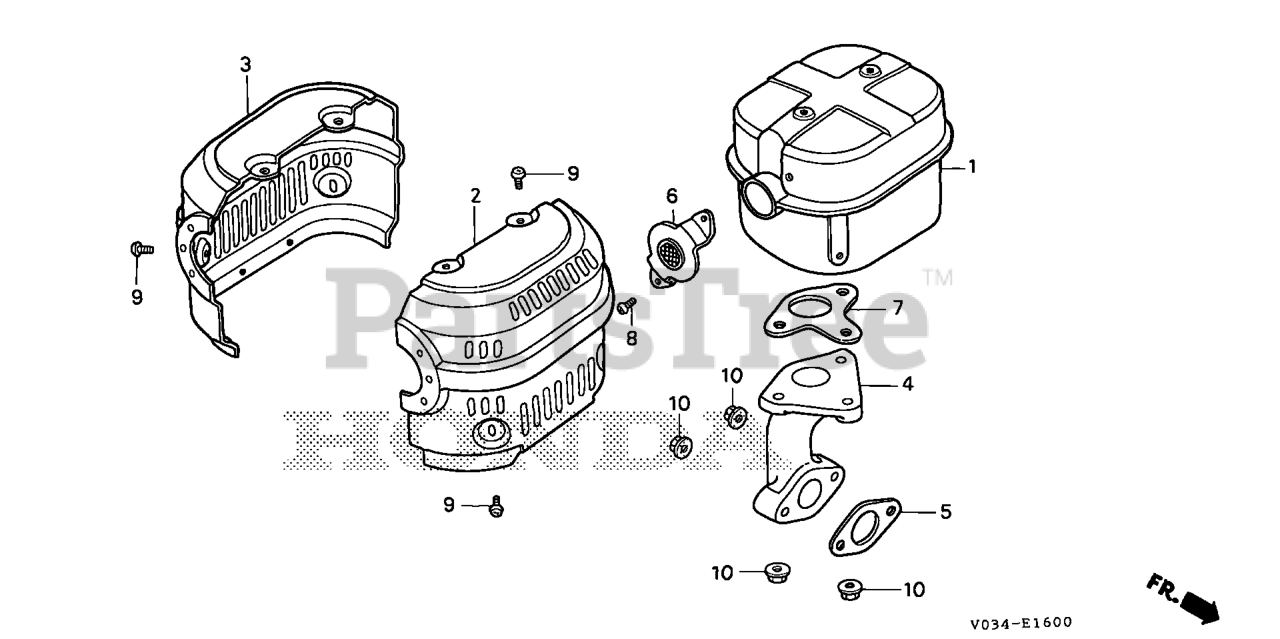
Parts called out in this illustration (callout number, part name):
1	MUFFLER
2	PROTECTOR, R. MUFFLER
3	PROTECTOR, L. MUFFLER
4	PIPE, EX.
5	GASKET, EX. PIPE Use up to Engine SN 2949254.
5	GASKET, EX. PIPE (WACKER)
6	FLANGE, BAFFLE
7	GASKET, MUFFLER
7	GASKET, MUFFLER (NIPPON LEAKLESS)
8	SCREW, TAPPING (5X8)
9	SCREW, TAPPING (5X8)
10	NUT, FLANGE (8MM)
